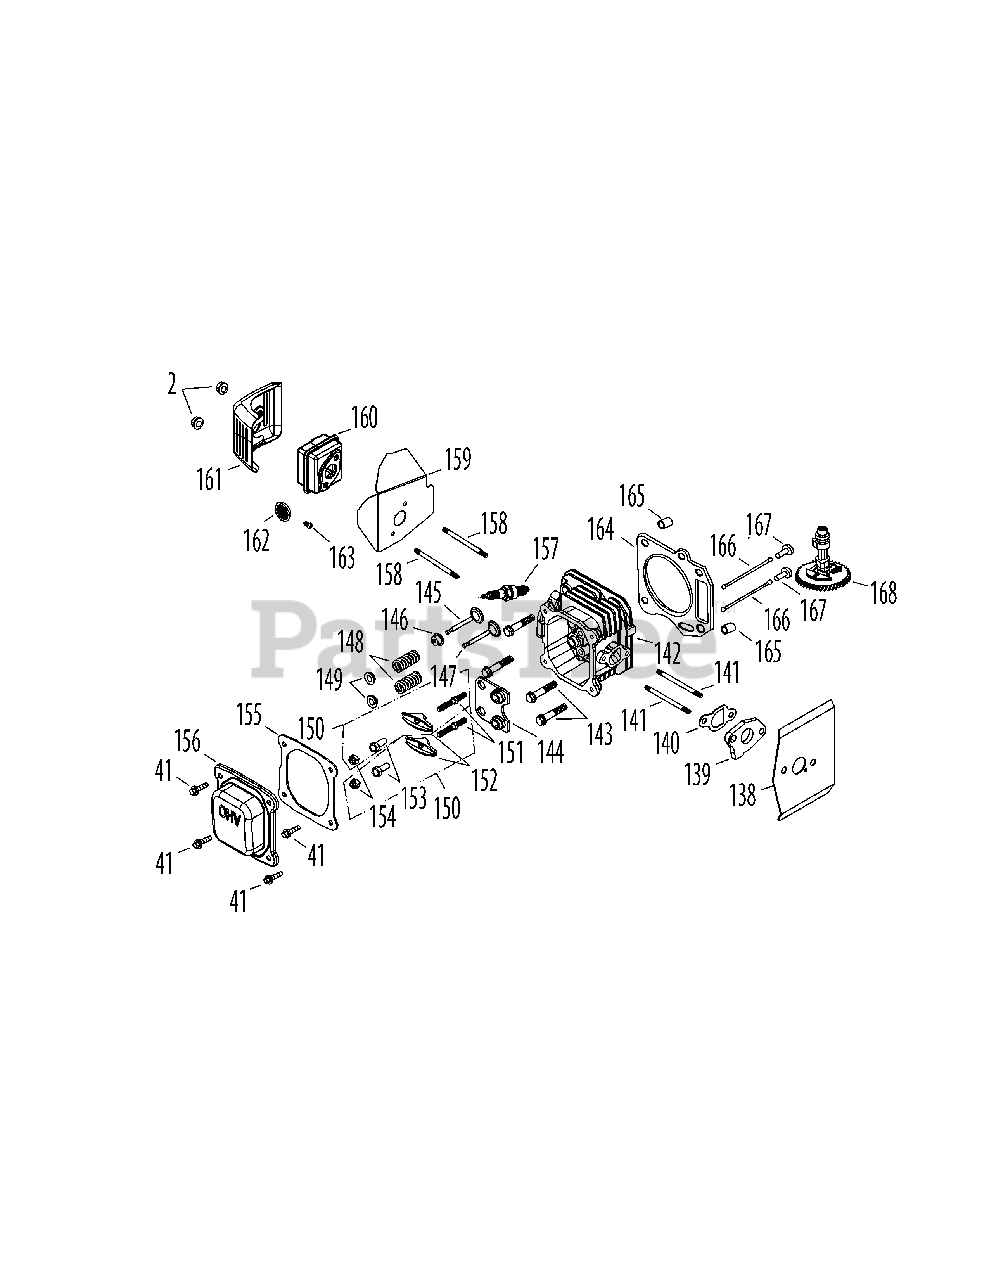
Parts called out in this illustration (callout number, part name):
2	Nut M6 X 10 Mm
41	Bolt M6×14
138	Carburetor Gasket
139	Carburetor Insulator
140	Carburetor Insulator Gasket
141	Carb Stud M6x92
142	Cylinder Head
143	Head Bolt M8×54
144	Push Rod Guide
145	Intake Valve
146	Intake Valve Seal
147	Exhaust Valve
148	Valve Spring
149	Valve Spring Retainer
150	Rocker Arm Assembly
151	Rocker Arm Stud
152	Rocker Arm
153	Fulcrum Nut
154	Jam Nut
155	Valve Cover Gasket
156	Valve Cover
157	Spark Plug
158	Muffler Stud M6x95
159	Muffler Gasket
160	Muffler Assembly
161	Muffler Shield
162	Spark Arrestor
163	Spark Arrestor Screw
164	Cylinder Head Gasket
165	Cylinder Head Dowel 10x16
166	Push Rod (2 per order)
167	Tappet
168	Camshaft Assembly
